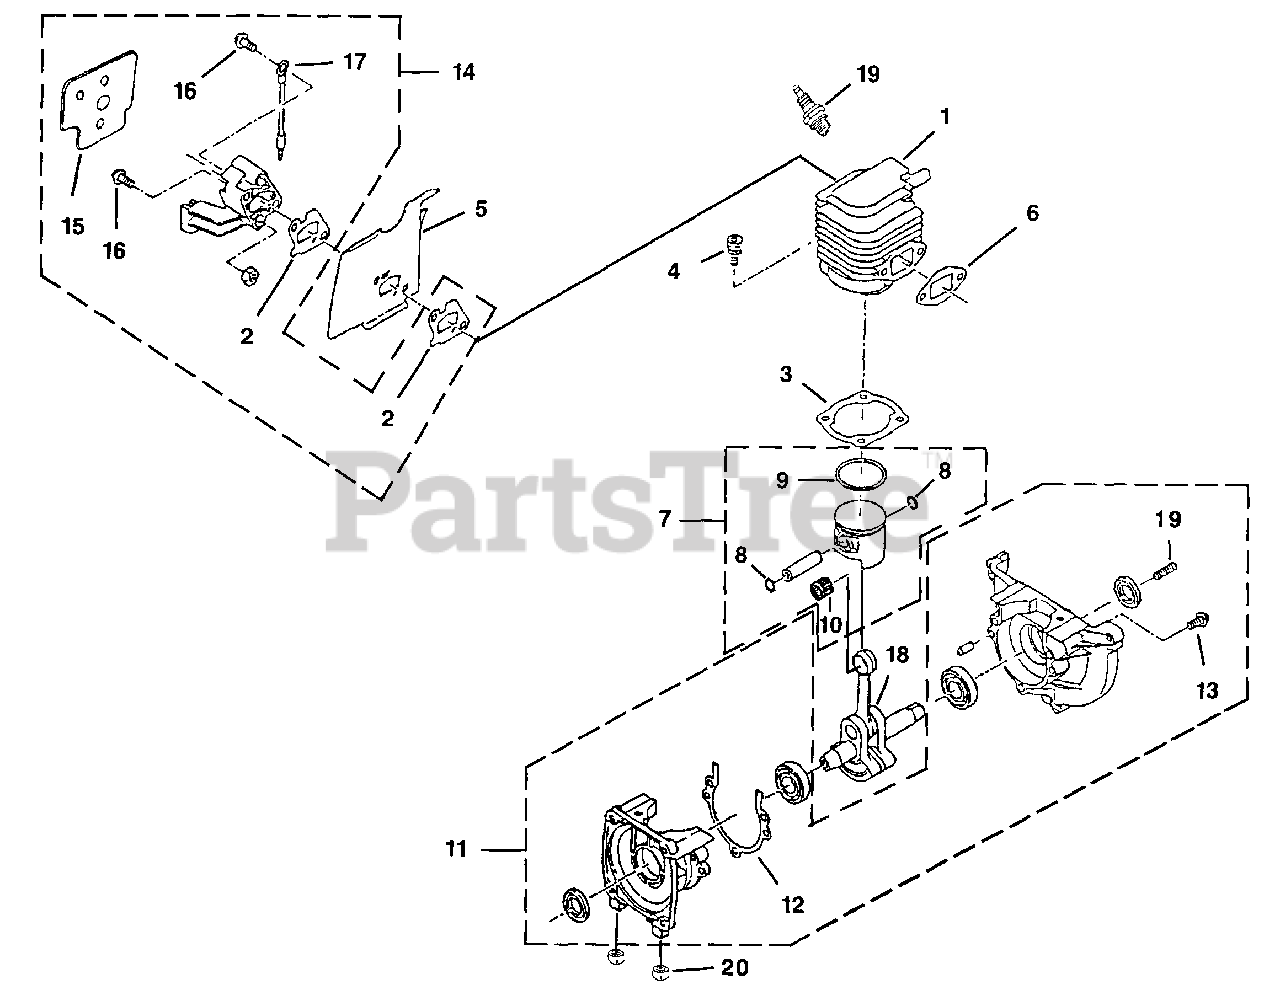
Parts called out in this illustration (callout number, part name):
1	CYLINDER ASSEMBLY
2	GASKET-Heat Dam
3	GASKET-Cylinder
4	SCREW-Socket HD (M5 x 20 W SW)
5	INSULATOR-Carburetor
6	GASKET-Muffler
7	PISTON ASSEMBLY
8	RING-Retaining
9	RING-Piston
10	BEARING, Wrist Pin
11	CRANKCASE ASSEMBLY
12	GASKET-Crankcase
13	SCREW (M5 x 25)
14	HEAT DAM ASSEMBLY
15	GASKET-Carburetor
16	SCREW-Socket Hd
17	WIRE-Ground
18	CRANKSHAFT COMPLETE
19	STUD, Crankshaft
20	RUBBER BUMPER KIT
